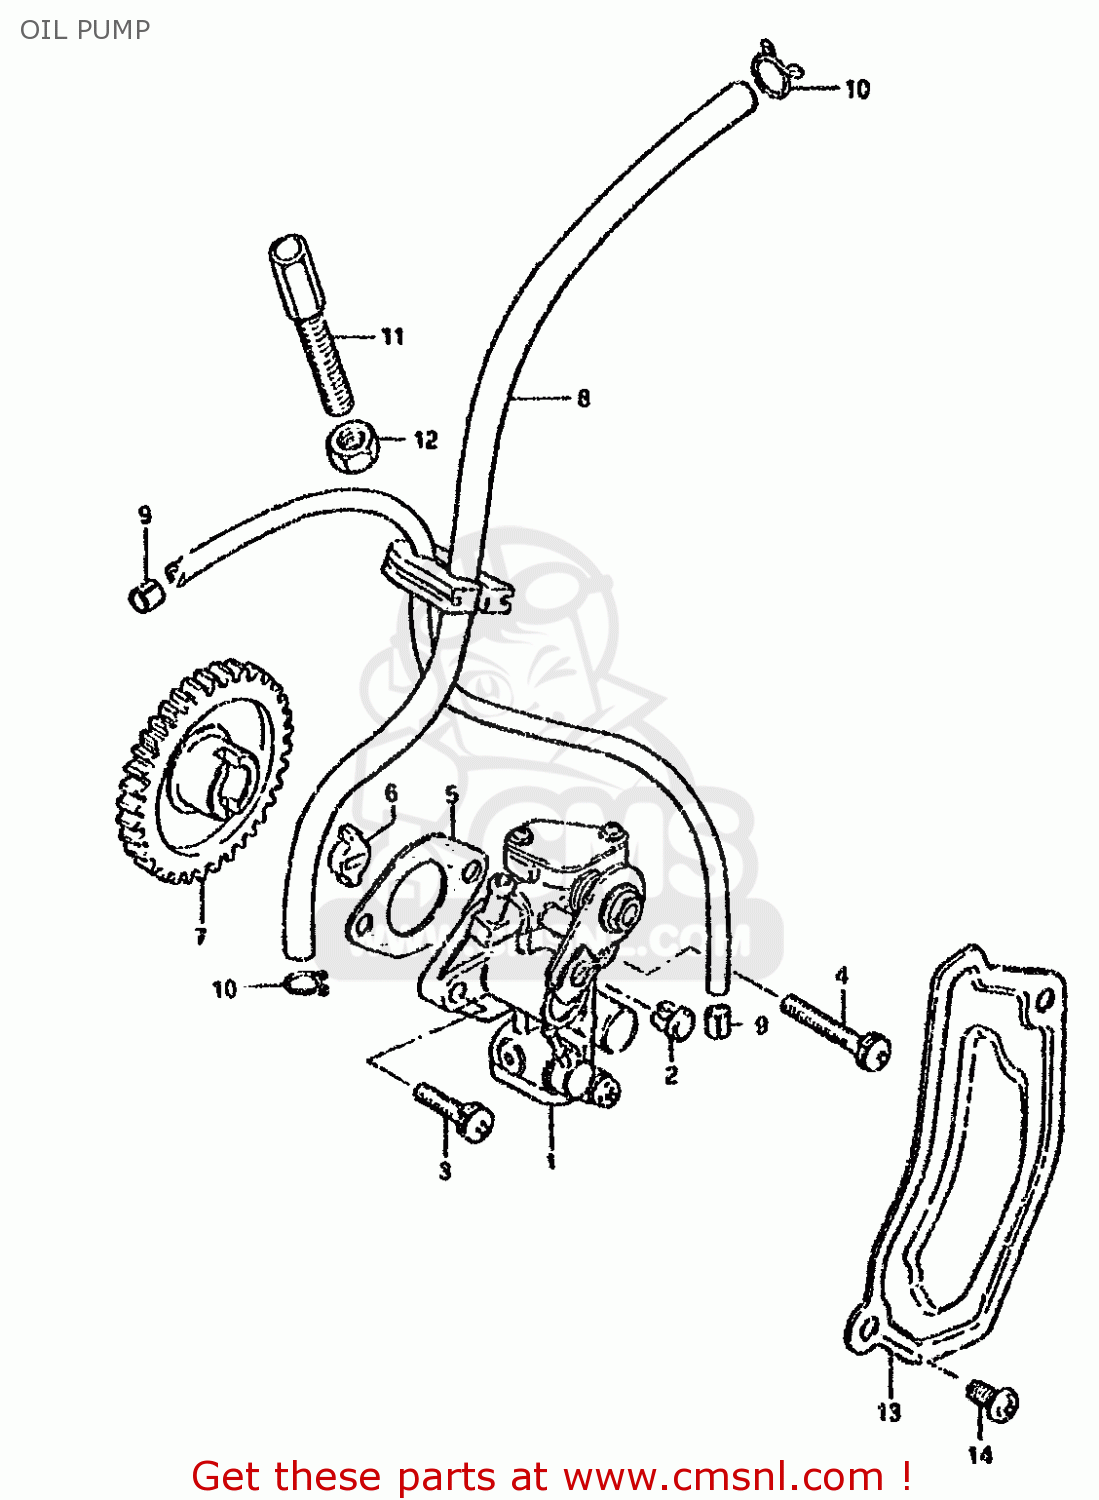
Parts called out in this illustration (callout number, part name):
1	PUMP ASSY,OIL
2	TERMINAL,CABLE
3	SCREW
4	SCREW
5	GASKET,OIL PUMP (NAS)
6	PIECE,OIL PUMP DRIVE
7	GEAR,OIL PUMP DRIVE
8	HOSE,OIL NO.2
9	CLIP
10	CLIP
11	BOLT
12	NUT
13	CAP,OIL PUMP INSPECTION
14	SCREW
